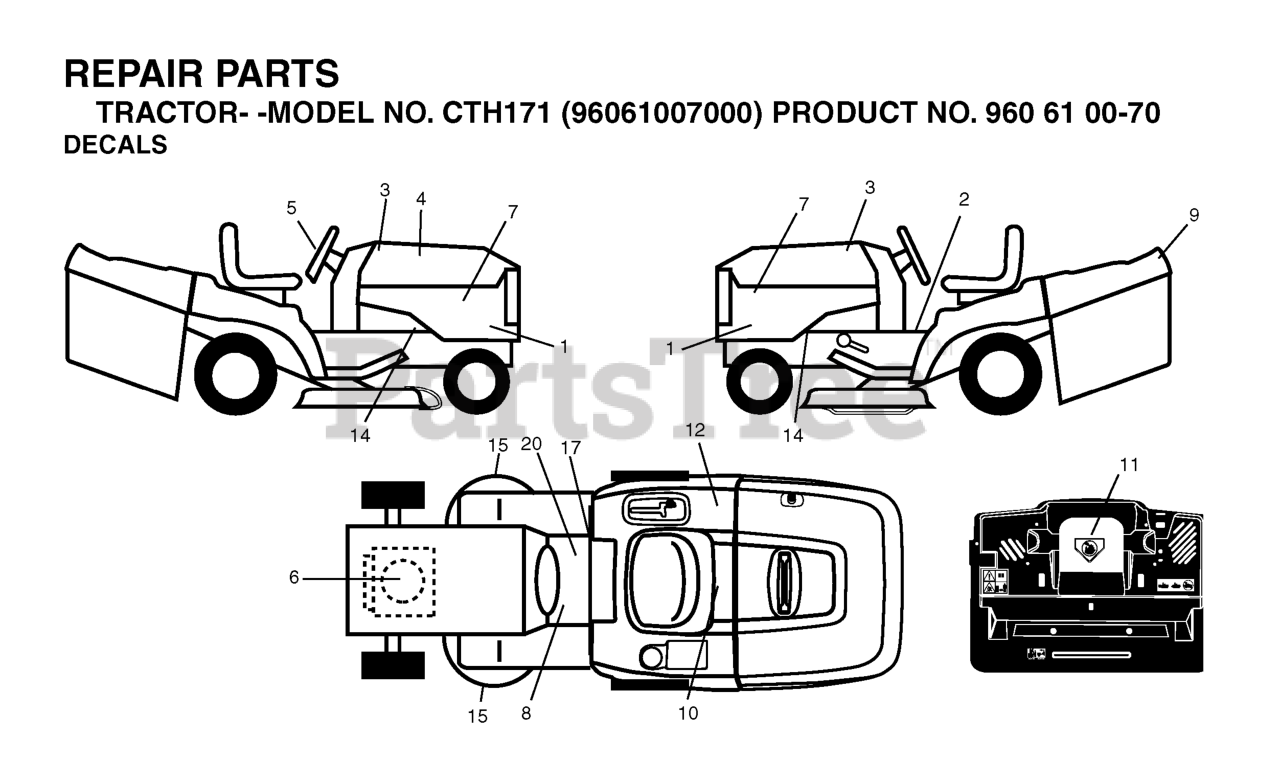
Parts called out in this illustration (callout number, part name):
2	LABEL
5	DECAL.STEERING.HUSQ.BLUE
6	DECAL
7	DECAL.HOOD.HUSQVARNA.INTERNATI
8	DECAL
10	DECAL BTRY SYMBOLS
11	DECAL.INTERNATIONL.CUTFINGER
12	Decal, Fender 100 DB/CE
17	DECAL PARK BRAKE
20	DECAL.BYPASS.FENDER.CRD.LT.YT
